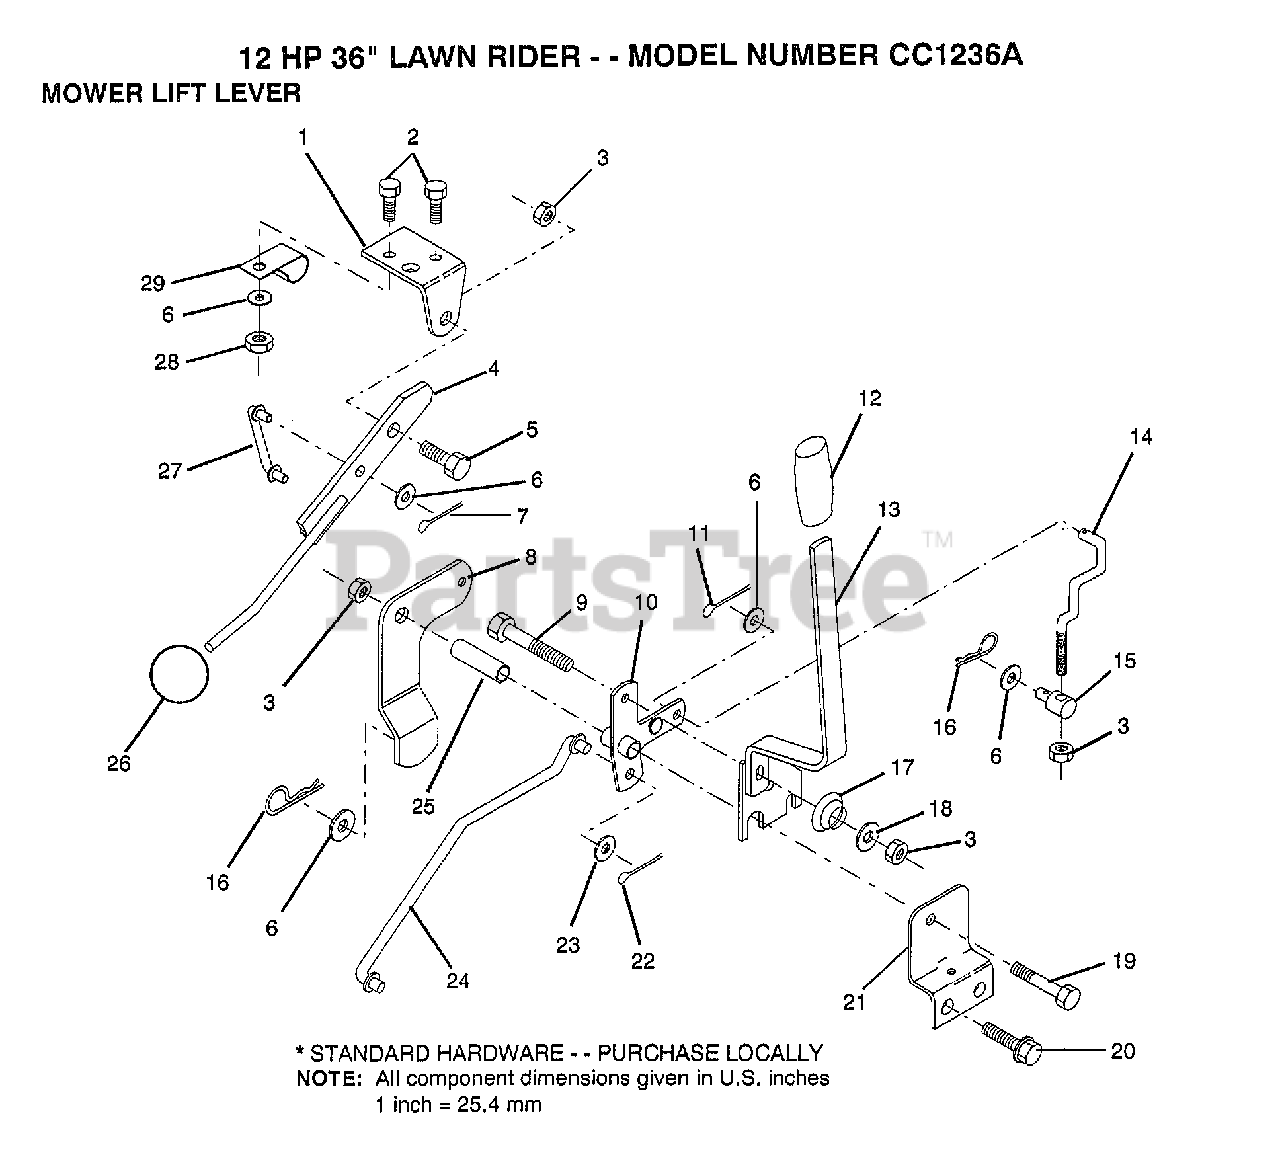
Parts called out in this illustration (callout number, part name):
1	BRKT CLUTCH
2	BOLT
4	CLUTCH LEVER AS
5	"BOLT, SHOULDER LT"
6	WASHER
8	CLUTCH ARM ASS'Y
9	BOLT
10	"BELLCRANK,LIFT"
11	COTTER PIN
12	GRIP HANDLE
13	"HDLE,LIFT T"
14	"LINK,LIFT FRT"
16	SPRING.RETAINER
17	SPRING COMPRESSIO
18	WASHER T
19	BOLT
20	SCREW LT
21	"BRKT,MOWER HGT"
22	PIN COTTER 1/8
24	"ROD,MOWER LIFT "
25	TUBE SPACER
26	KNOB T(3/8 HOLE)
27	"LINK,MOWER LIFT"
29	"CLIP,INSULATOR"
